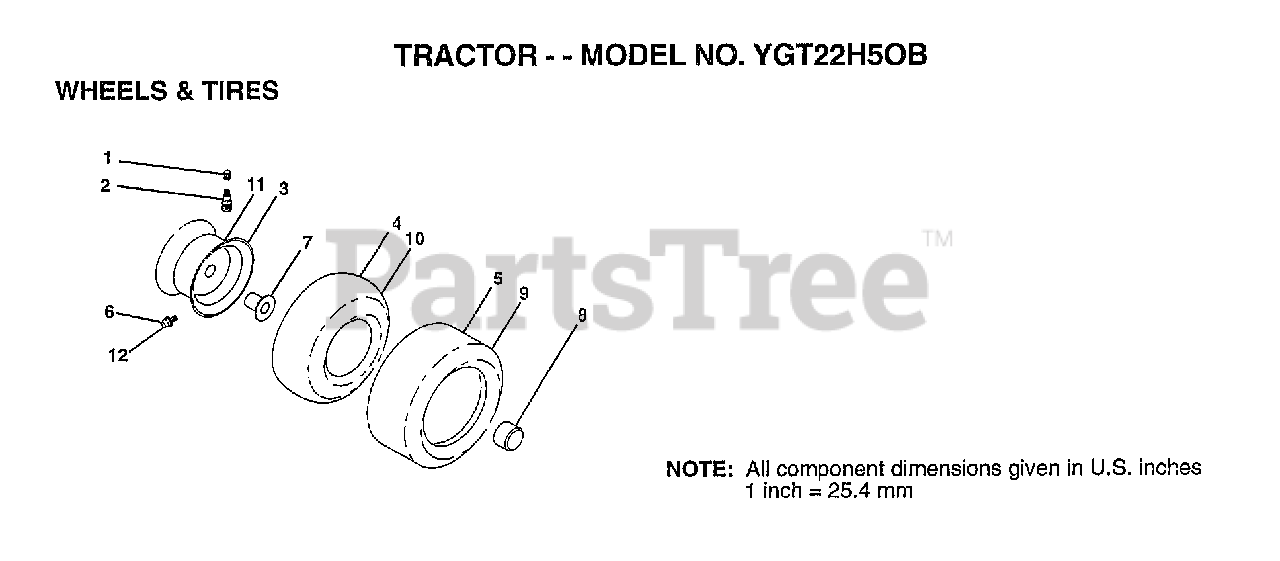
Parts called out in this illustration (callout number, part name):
1	VALVE CAP
2	VALVE STEM LT
3	"RIM ASM 8"" FRT"
4	TUBE.16X6.5/7.5-8
6	FITTING LT
7	"FLANGE, BEARING"
8	HUB CAP
10	TUBE.23X8/10-12
11	"RIM ASM 12"" REAR"
12	ZERK FITTING M
